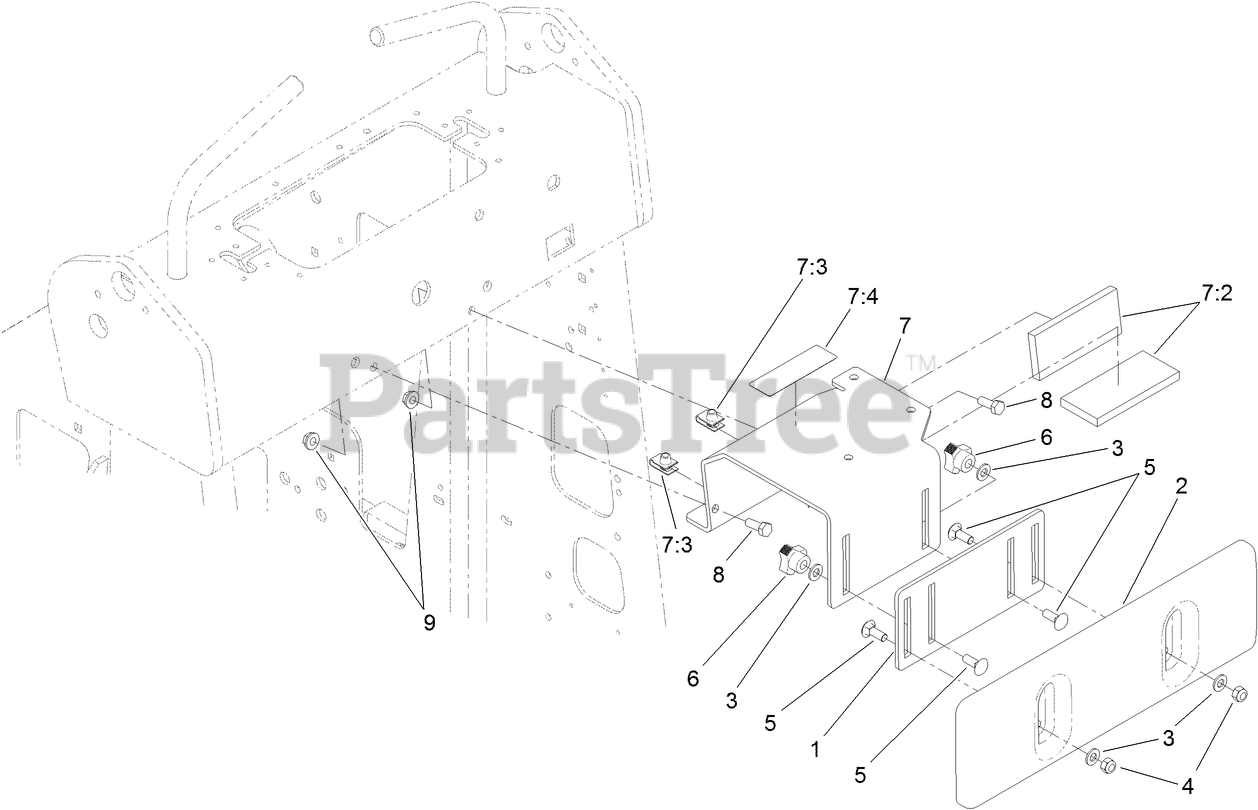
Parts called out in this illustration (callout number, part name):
1	PLATE-ADJUSTING
2	SUPPORT-THIGH
3	WASHER-FLAT
4	NUT-LOCK, NI
5	SCREW-CARR
6	Knob-Adjustment
7	CANISTER BRACKET ASM
7:2	PAD-FOAM
7:3	NUT-CLIP, U
7:4	DECAL-MANUAL
8	SCREW-HH
9	NUT-HF
